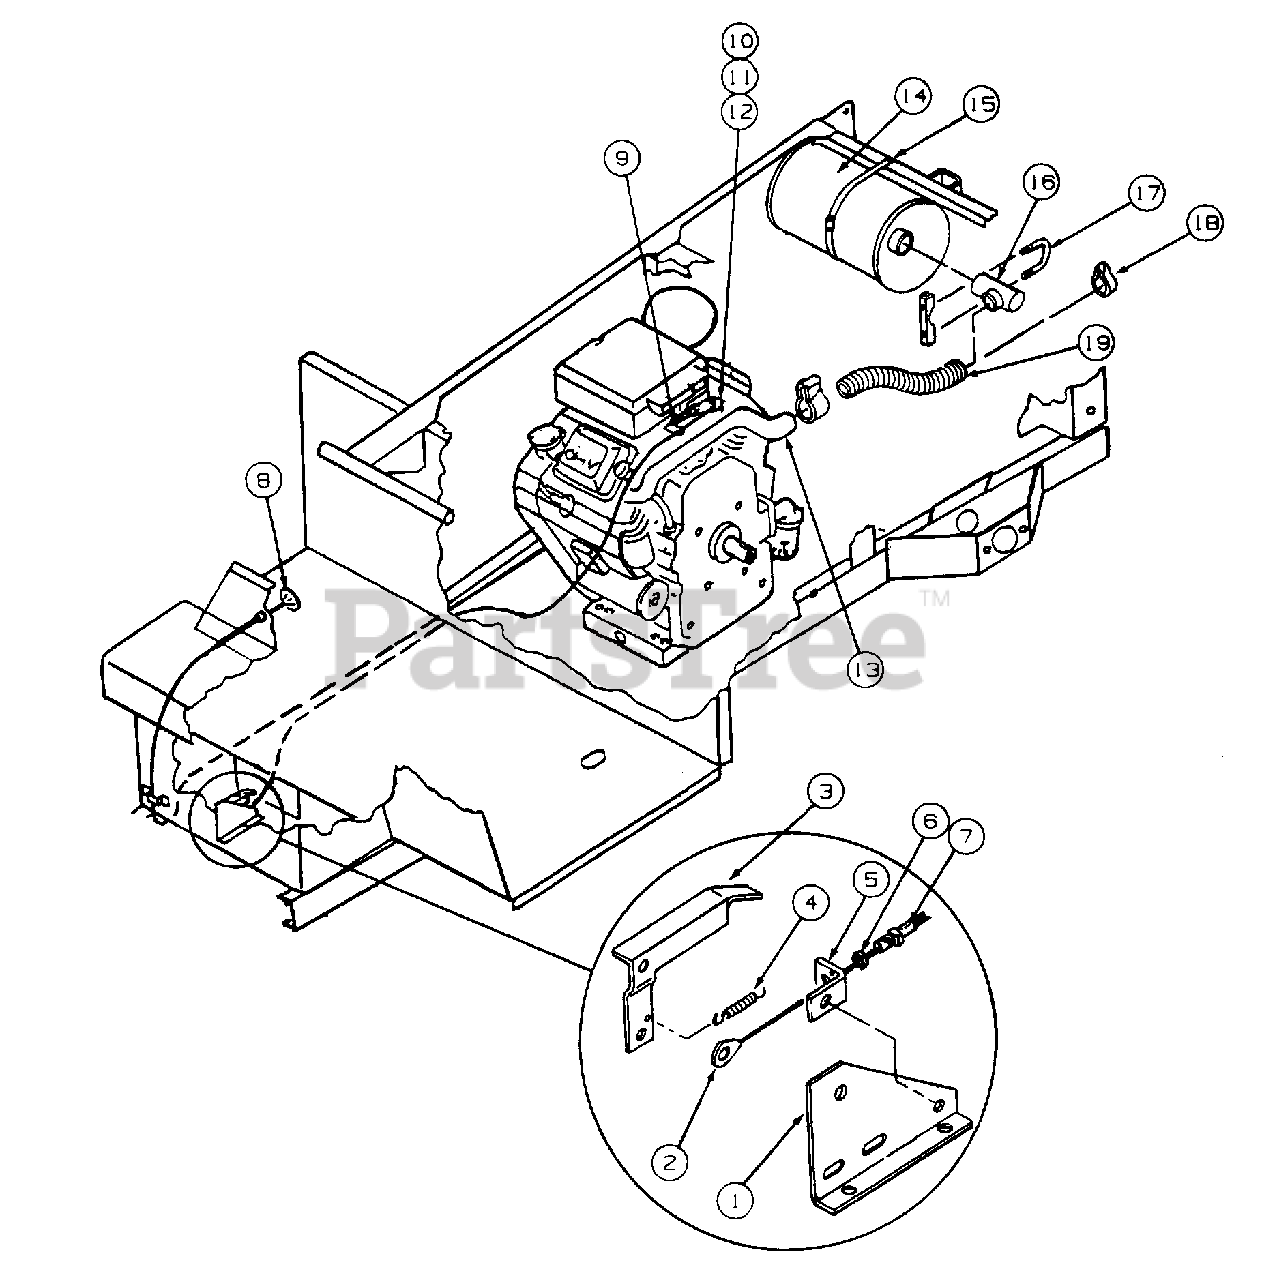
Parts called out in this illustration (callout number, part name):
1	Bracket, Accelerator Mtg
2	Cable, Inner, 64"
3	Pedal, Accelerator
4	Spring, Accelerator Extension
5	Bracket, Accelerator Angle
6	Nut, Hex, .31-24 UNF
7	Cable, Outer, 60"
8	Cable, Choke
9	Spring, Throttle
13	Manifold, Exhaust
15	Clamp, Adjustable
16	Adaptor, Exhaust, Single
17	Clamp, Muffler, 1-1/2
18	Clamp, Muffler, 1-3/16
19	Tube, Stainless Flex, 13"
